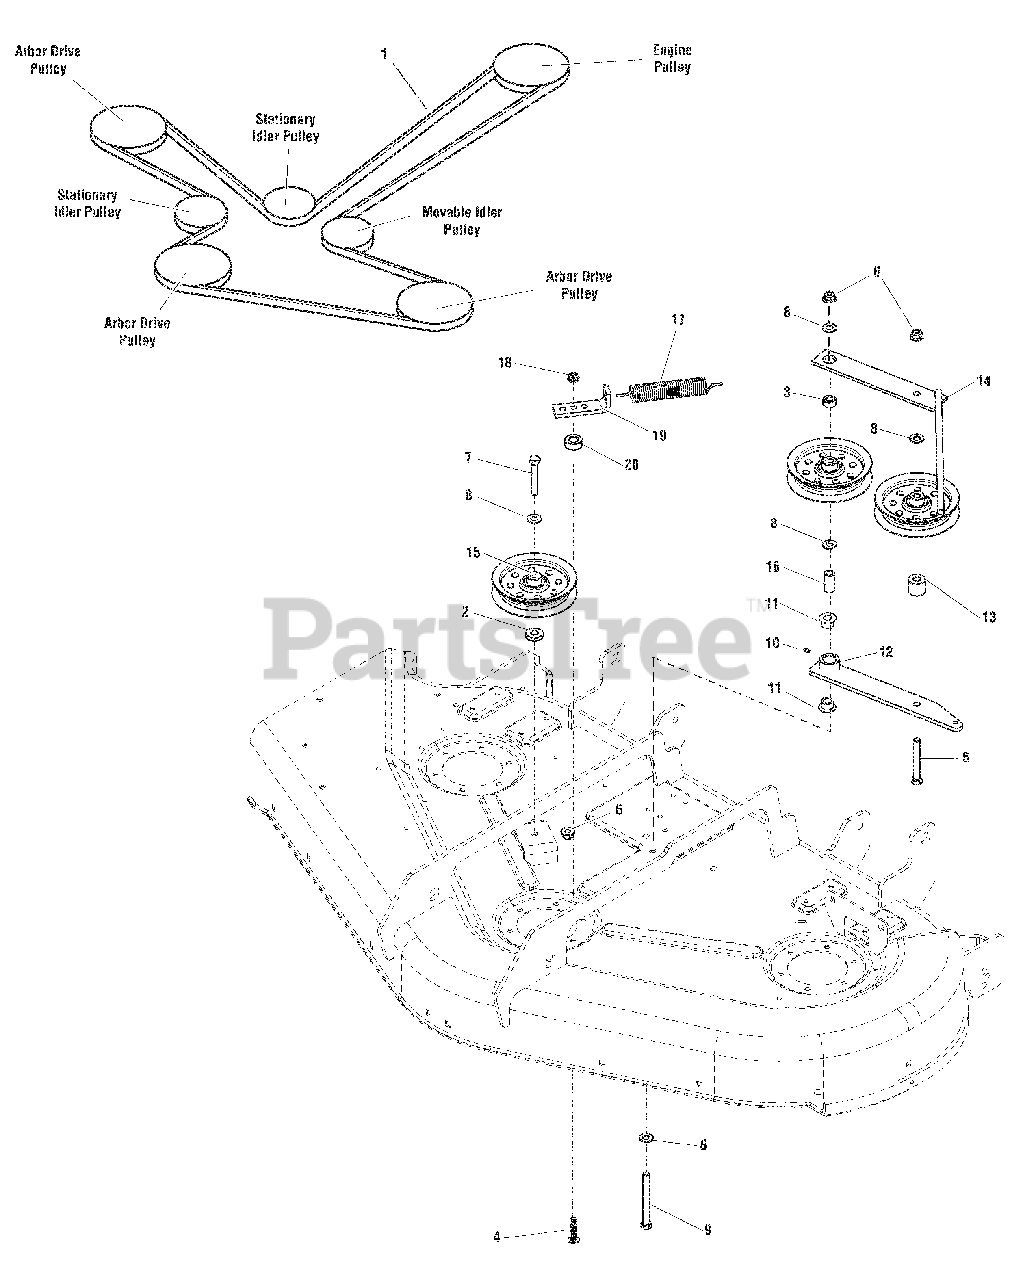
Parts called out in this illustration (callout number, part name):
1	BELT, HA-SEC, 155.13EL, ARAMID, WRPD
2	SPACER, .39 X 1.00 X .25
3	SPACER, .39 X .75 X .38
4	BOLT, 5/16-18 X 1 1/2 FLANGE
5	BOLT, 3/8-16 X 2-3/4" GD5 CZ
6	NUT, 3/8-16 HEX NYLOCK FLANGE
7	BOLT, 3/8-16 X 2-1/4" GD5 CZ
8	WASHER, 3/8 SAE
9	BOLT, 3/8-16 X 3-1/2" GD5 CZ
10	GREASE FITTING, 1/4-28 STRAIGHT
11	BUSHING, 0.628IDX0.751ODX0.400LG PWDR MTL
12	WELD, IDLER ARM, 44" SNAPPER - RED
13	SPACER, .39 X 1.00 X .88
14	WELD, MOUNT, IDLER, TENSION
15	PULLEY, IDLER, 4.06OD, .669ID, .75W STL
16	SPACER, 0.39 IDX0.625ODX1.15 LG CASE HARD
17	SPRING, EXTENSION, 1.00
18	NUT, 5/16-18 HEX NYLOCK FLANGE
19	ANCHOR, SPRING
20	SPACER, .52 X 1.00 X .44
